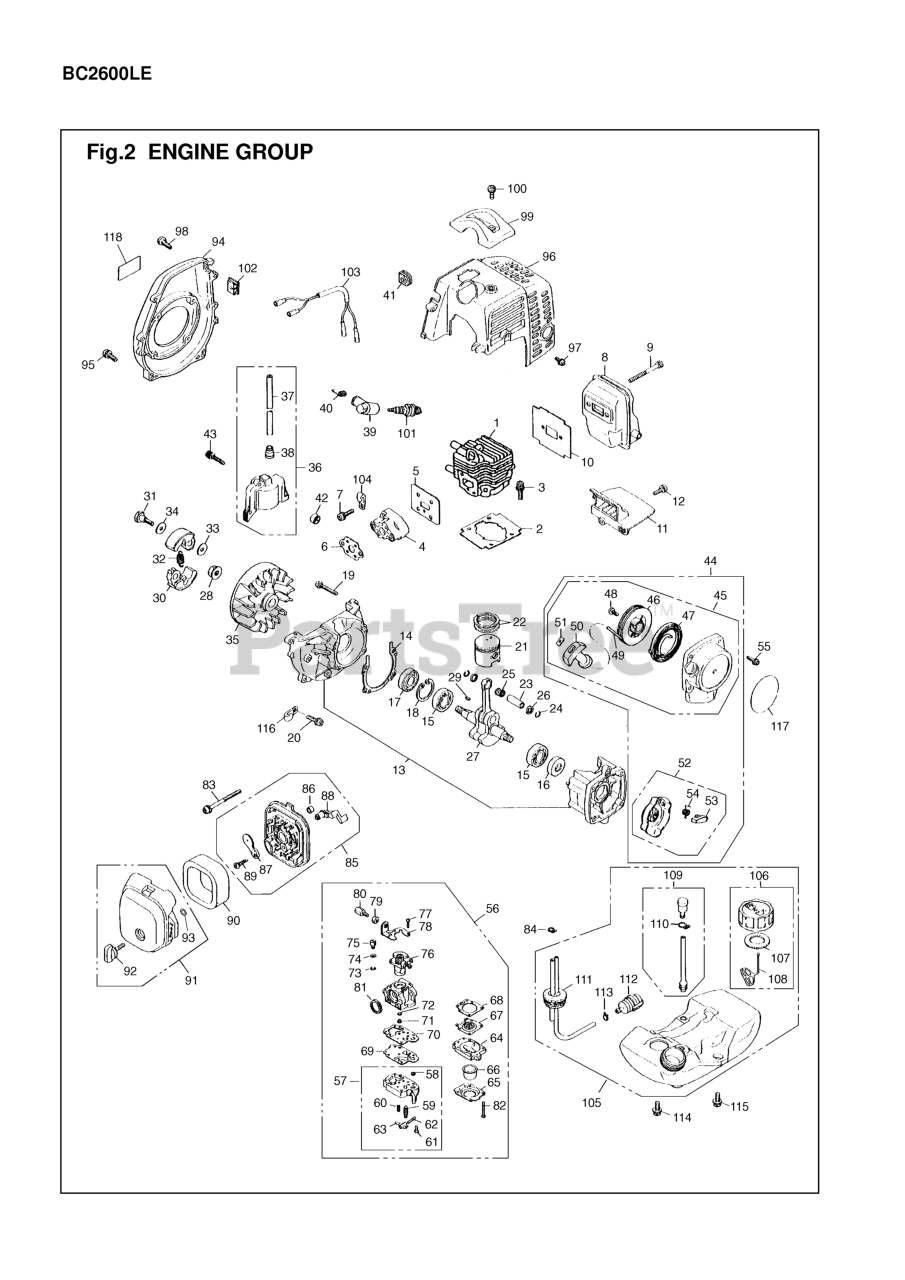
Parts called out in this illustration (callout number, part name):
3	BOLT, M5 X 22
7	SCREW, M5X20 (RPLS.1400-75510)
9	BOLT, M5 x 50
10	GASKET, MUFFLER
13	CRANKCASE
15	BEARING
16	SEAL, OIL (RPLS 1100-21210)
17	SEAL
18	RING
19	BOLT, M5 X 30
21	PISTON
22	RING, PISTON
23	PIN
24	RING
26	WASHER
27	CRANKSHAFT (RPLS 1850-42000)
28	NUT
29	KEY
30	SHOE, CLUTCH (RPLS -51110)
31	BOLT
32	SPRING, CLUTCH (RPLS-51220)
33	WASHER
34	WASHER
35	ROTOR
36	COIL ASSY (RPLS 5500-71200)
37	CORD
38	CAP
40	SPRING
41	GROMMET
42	SPACER
43	BOLT
45	RECOIL ASSEMBLY
46	REEL
47	SPRING
48	SCREW (RPLS -75150)
50	KNOB
51	PLATE, STOPPER
52	PULLEY ASSY (RPLS -75210)
53	RATCHET (RPLS 1850-75220)
54	SPRING, RETURN
56	CARBURETOR ASSYxxx
57	BODY ASSY
59	VALVE
60	SPRING, METERING LEVER
61	SCREW, METERING LEVER PIN
62	PIN
63	LEVER
64	BODY
65	COVER
66	PUMP
67	DIAPHRAGM (USE 4810-81260)
68	GASKET, DIAPHRAGM
69	DIAPHRAGM
70	GASKET, PUMP
71	JET
72	O-RING
73	RING
74	WASHER
75	SWIVEL
77	SCREW
79	NUT
80	SCREW
81	RING, PACKING
82	SCREW
84	CLIP
85	BODY-A (RPLS -82101)
86	SLEEVE
87	PLATE, CHOKE (RPLS-82130)
88	LEVER
89	SCREW
90	ELEMENT
92	KNOB
93	RING
94	COVER, FAN (RPLS-31110)
97	SCREW, M5 x 12
98	SCREW, HOUSING
99	GUARD, PLUG
103	CORD COMPLETE
104	CLAMP
105	TANK ASSY
106	CAP ASSY
107	PACKING
108	STOPPER (RPLS 3317-57240)
109	BREATHER ASSY (RPLS -85601)
110	CLIP
111	PIPE COMPLETE
112	FILTER (RPLS 1850-85300)
113	CLIP
114	SCREW
115	SCREW W/ WASHER
116	CLAMP
117	LABEL, RECOIL
118	LABEL, COVER
